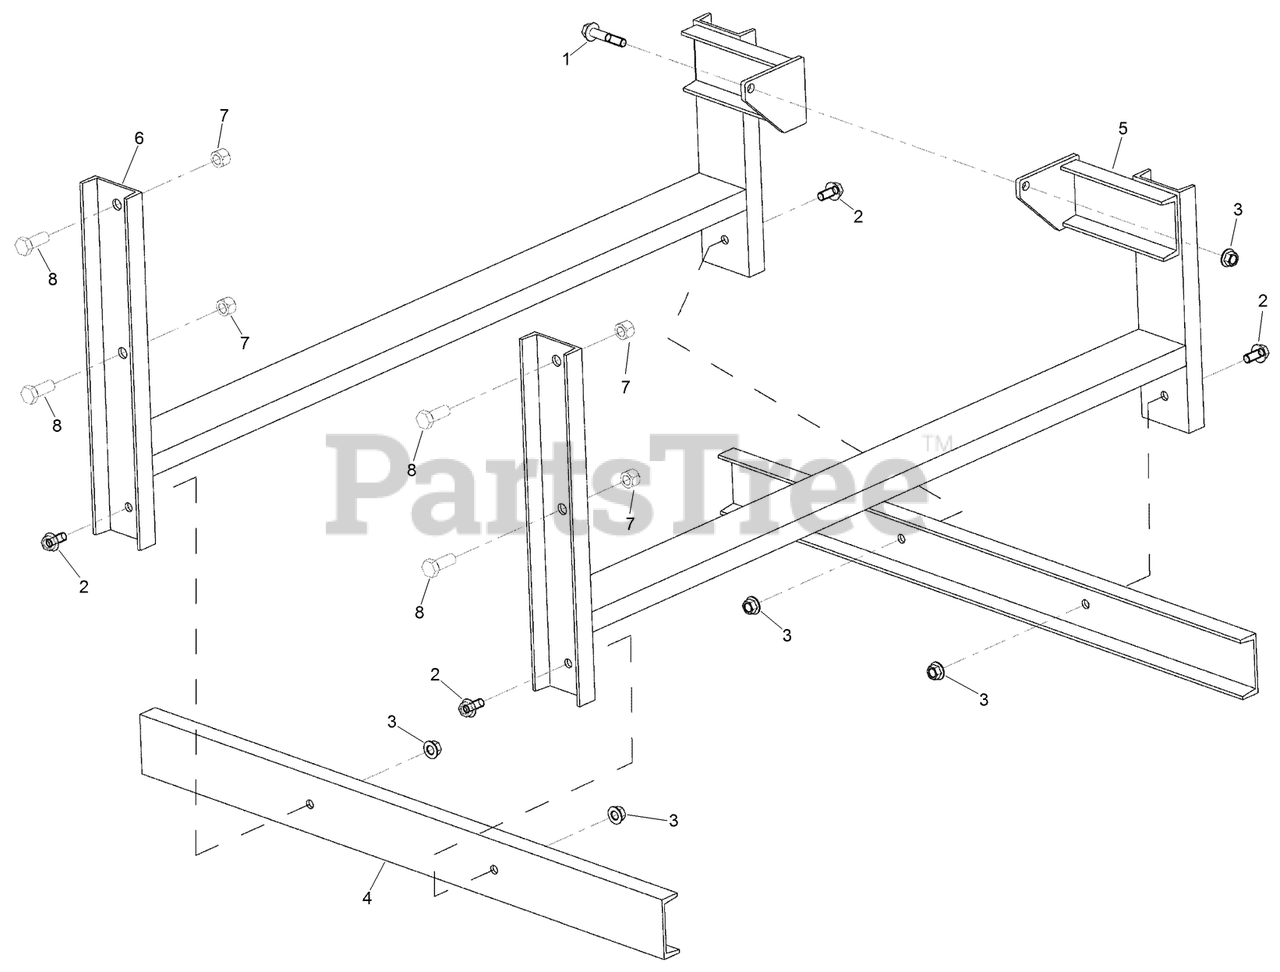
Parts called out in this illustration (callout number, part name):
1	SCREW, METRIC FLANGE w/BODY - M20 x 100
2	SCREW, METRIC FLANGE FULL - M20 x 40
3	NUT, METRIC HEX FLANGE - M20, Zinc
4	CHANNEL
5	STAND - RH
6	STAND - LH
